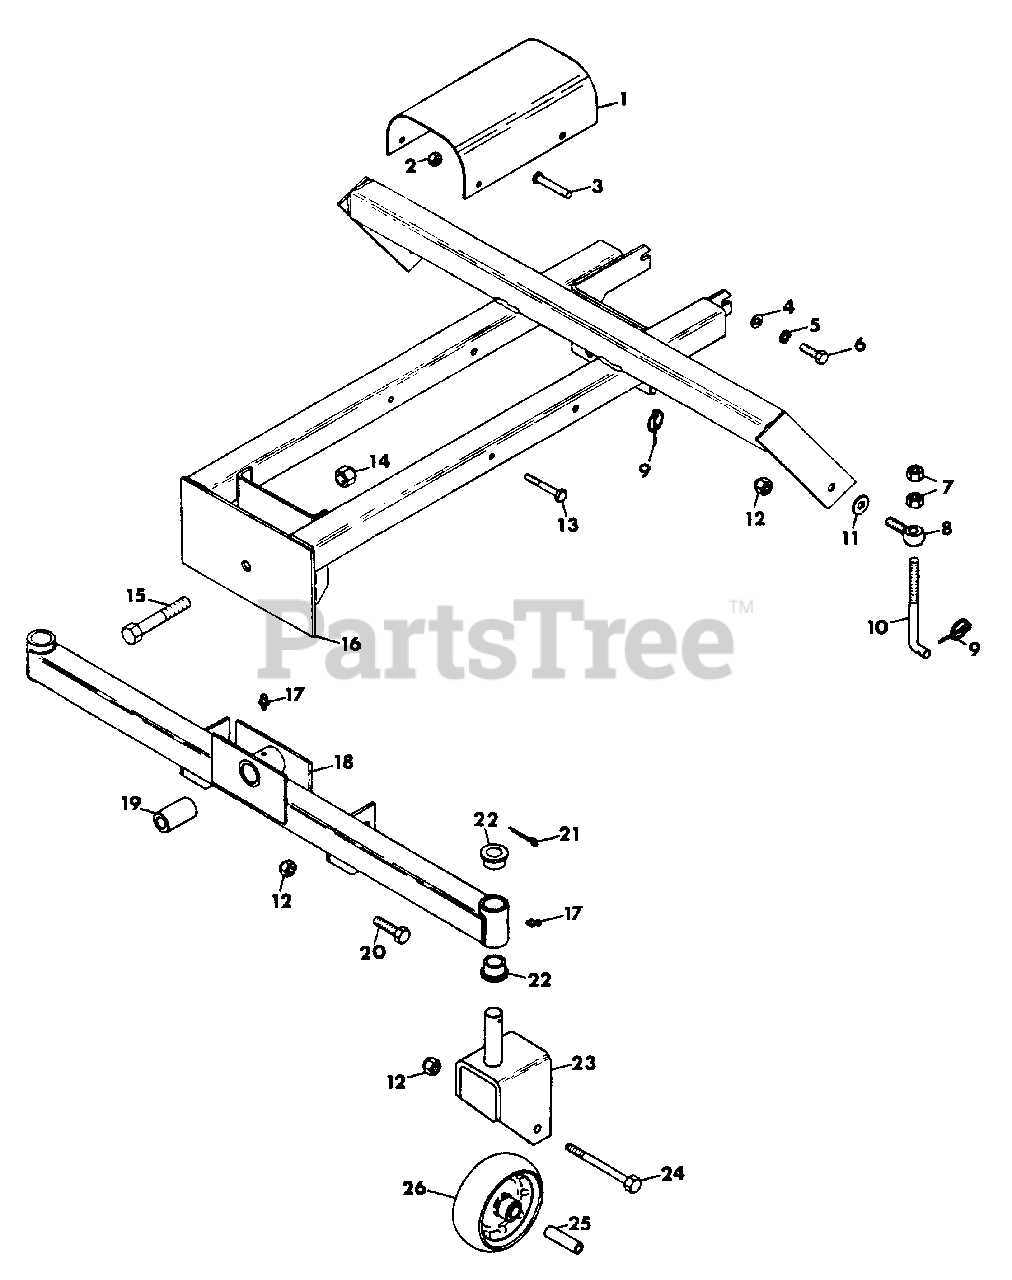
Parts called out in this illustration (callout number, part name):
1	GUARD, PTO SHAFT
2	NUT, LOCK 5/16-18
3	PIN, CLEVIS
4	WASHER, FLAT .406X.812X.065
5	WASHER, LOCK 3/8
6	BOLT, HEX 3/8-16X1.00
7	NUT, JAM 1/2-13 HEX
8	BOLT, EYE
9	PIN, KLIK
10	ROD, HEIGHT ADJUSTMENT
11	WASHER, FLAT .500X1.250X.083
12	NUT, LOCK 1/2-13
13	BOLT, HEX 5/16-18X2.5
14	NUT, LOCK 3/4-10
15	BOLT, HEX 3/4-10X4.5
16	FRAME, MOWER
17	FITTING, LUBE 1/4-28
18	AXLE
19	TUBE, PIVOT
20	BOLT, HEX 1/2-13X1.375
21	PIN, COTTER 3/16X1.625
22	BEARING, FLANGED
23	FORK, CASTER
24	BOLT, HEX 1/2-13X5.00
25	BUSHING, WHEEL .520X.750X3.312
26	WHEEL, GAUGE
